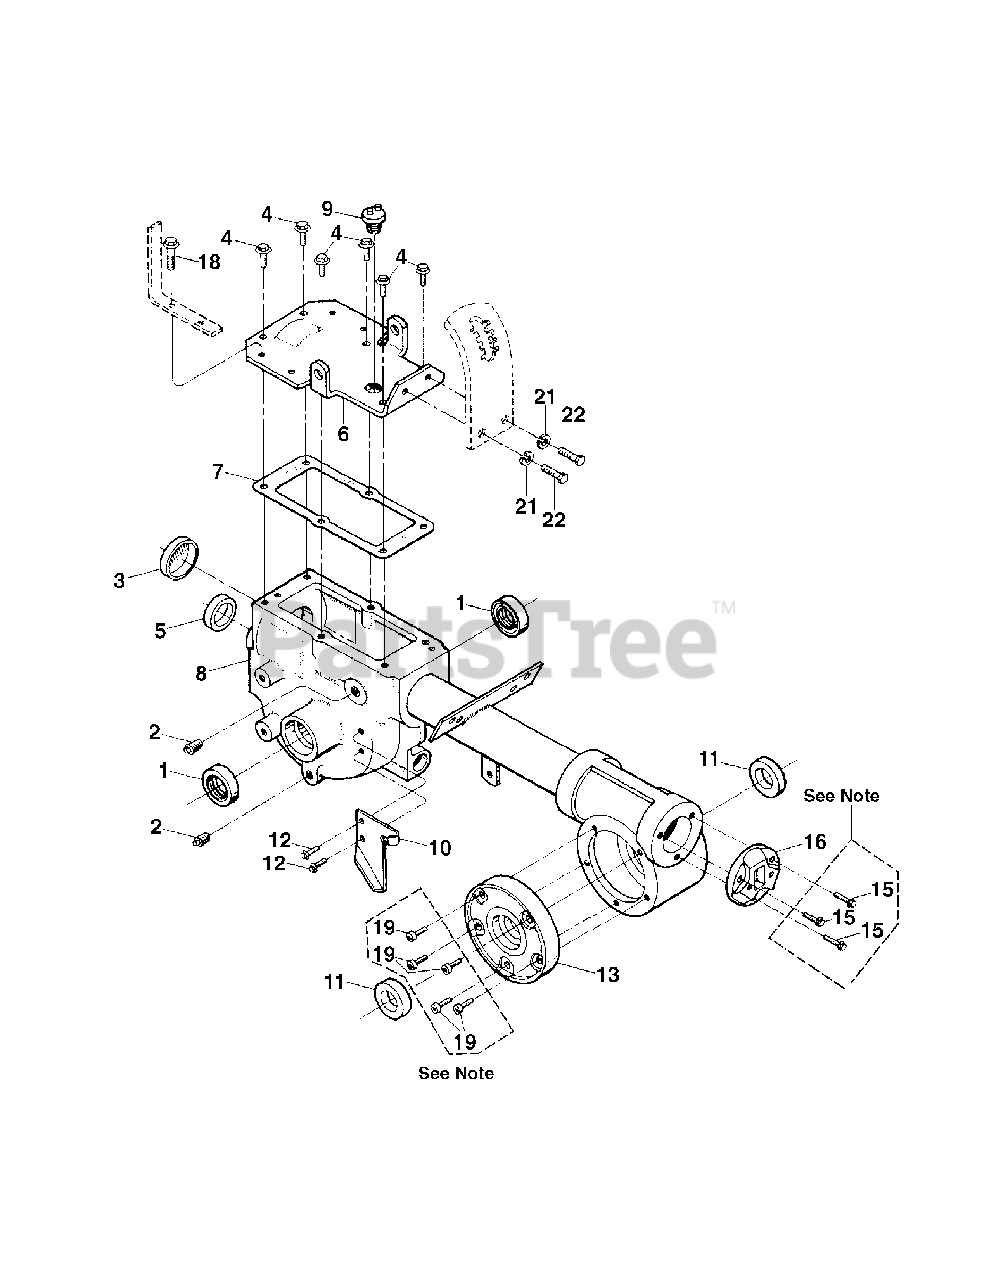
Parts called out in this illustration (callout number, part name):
1	Oil Seal (Double Lip), Wheel Shaft
2	Pipe Plug, 1/4
3	Seal, Transmission Bore
4	Hex Flange Screw, 5/16-18 x 3/4
5	Oil Seal, Input Pinion Shaft
6	Transmission Cover
7	Gasket, Transmission Top Cover
8	Transmission Case Assy
10	Mounting Plate, Wheel Clutch Cable
11	Oil Seal, Tiller Shaft
12	Screw, Hex Flange, 5/16-18 x 5/8"
13	Cover, Tiller Housing
15	Self-Sealing Screw, 1/4-20 x 7/8"
16	Rear Bearing Cap
17	Gasket, Rear Bearing Cap,.010"
18	Hex Flange Screw, 5/16-18 x 3/4
19	Self-Sealing Screw, 1/4-20 x 5/8'
21	Lockwasher, 3/8
22	Hex Hd. Screw, 3/8-16 x 5/8
